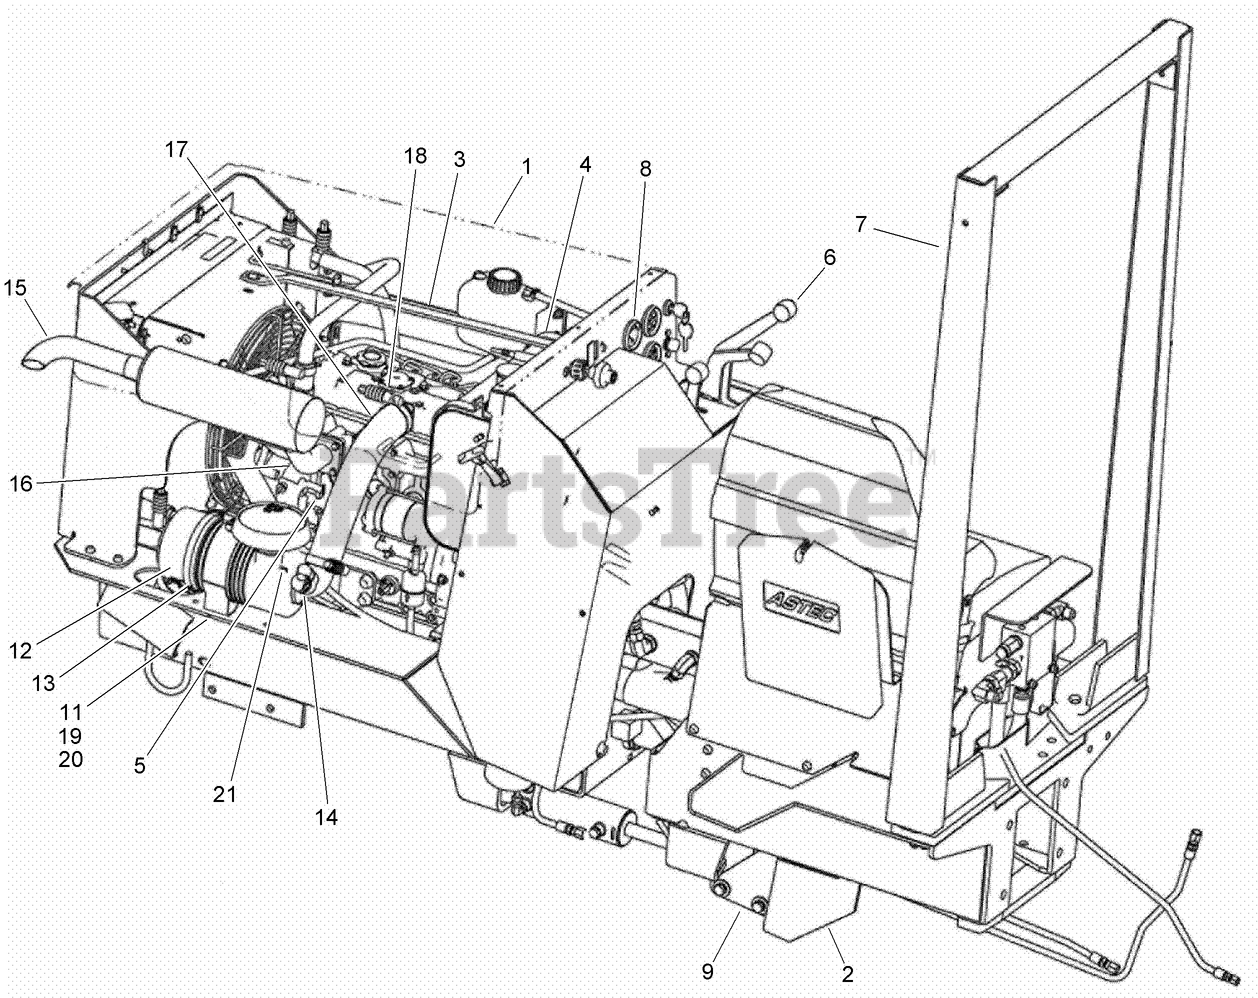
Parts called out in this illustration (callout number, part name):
1	GROUP - Chassis, Hood and Covers
2	POWER TRAIN GROUP
3	GROUP - Engine and Controls
4	HYDRAULIC PLUMBING REF
5	GROUP - FUEL SYSTEM REF
6	GROUND DRIVE CONTROLS REF
7	GROUP - Roll Over Protection System
8	INSTRUMENTS AND ELECTRICAL REF
9	BRAKE SYSTEM
11	BAND-AIR CLEANER
12	ASSEMBLY - Air Cleaner
13	HOOD-RAIN
14	SWITCH-PRESSURE, VACUUM
15	MUFFLER - Exhaust
16	HOSE - Radiator
17	HOSE - Air Cleaner
18	CLAMP-TORQUE, CONSTANT
19	NUT-TORQUE, PREVAILING
20	SCREW-HH
21	SCREW, METRIC FLANGE w/BODY - M12 x 25
